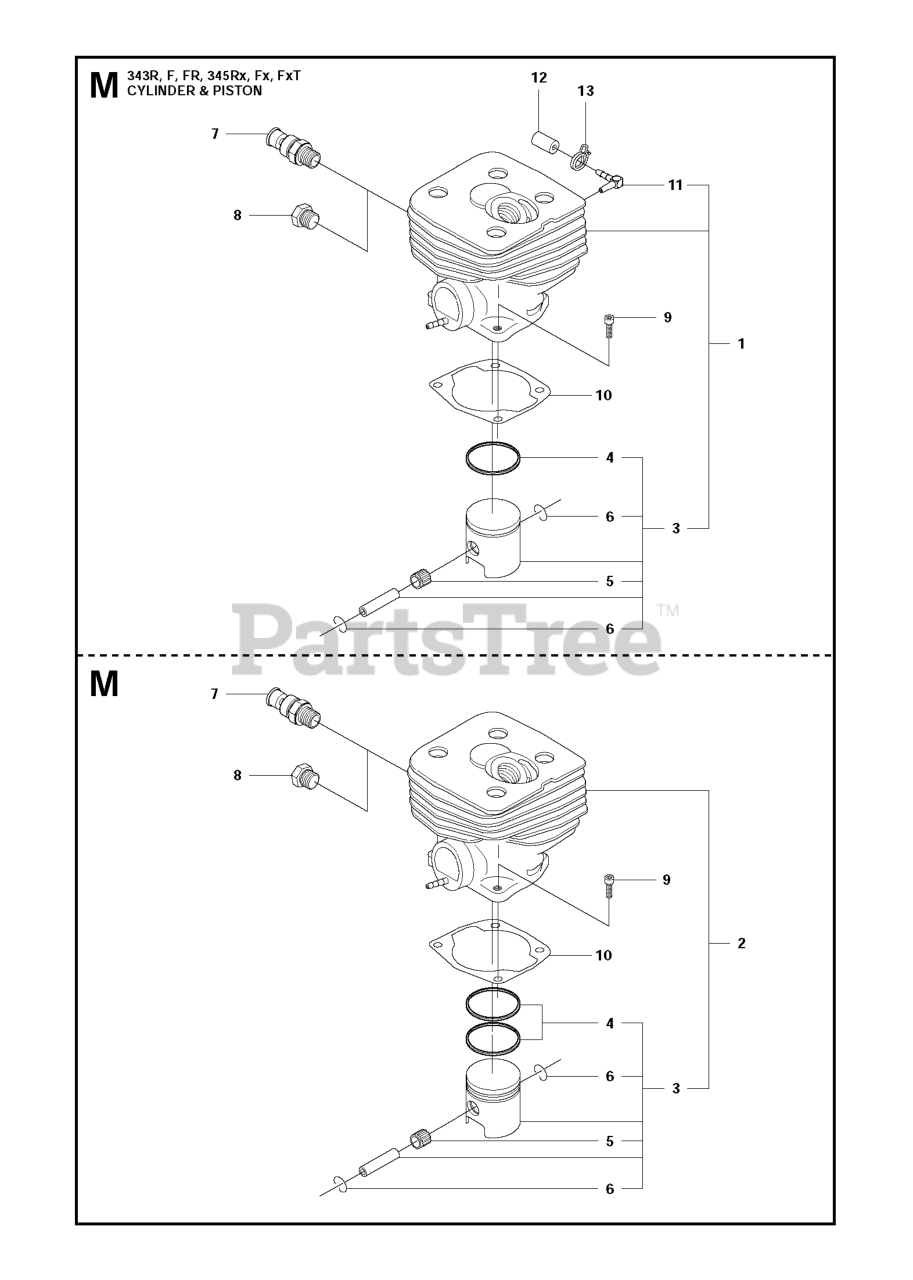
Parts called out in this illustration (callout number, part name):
1	CYLINDER
2	CYLINDER ASSY
3	PISTON ASSEMBLY
3	RP PISTON ASSY
4	PISTON RING
5	SUPPORT BUSHING
6	LOCKING RING
7	DECOMPRESSION VALVE
8	CYLINDER PLUG
9	SCREW MC6S 5X20
10	GASKET
11	NIPPLE
12	PROTECTIVE CAP
13	CLAMP
